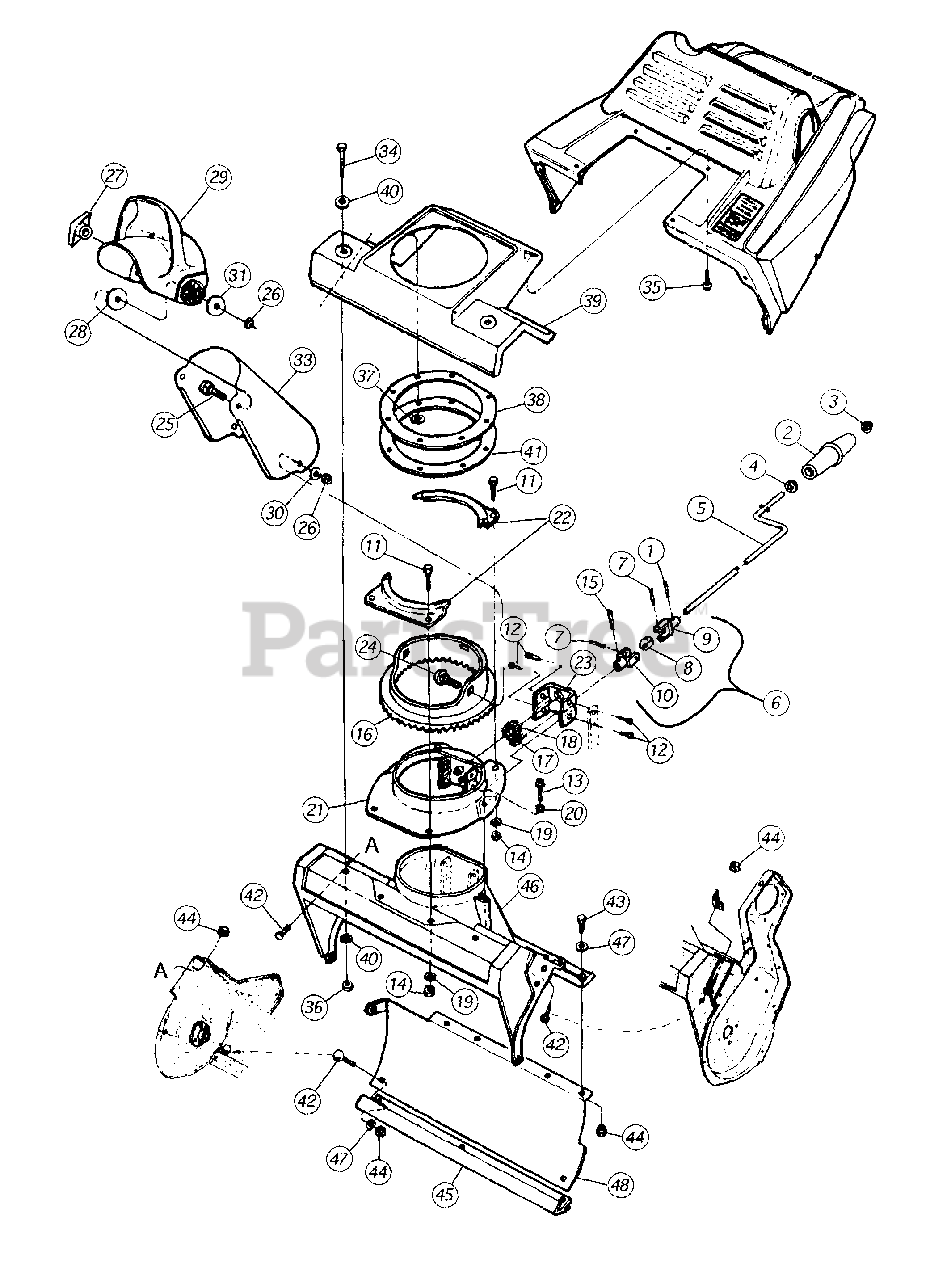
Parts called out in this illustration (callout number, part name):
1	Pin, Roll: 1/8 x .63
2	Chute Rotating Knob
3	Push Cap
4	Flat Washer
5	Chute Crank
6	U-Joint Assembly
7	Pin, Roll: 5/32 x .88
8	Connector, U-Joint
9	Clevis, Rear U-Joint
10	Clevis, Front U - Joint
11	Hex Screw: 1/4-20 x .75 Gr 5
12	Hex Screw: 1/4 x .50
13	Hex Screw
14	Top Lock Nylon Insert
15	Cotter Pin: 1/8 Dia. x 1.25
16	Chute Base: Black
17	Gear, Drive
18	Gear, Idler
19	Flat Washer
20	Flat Washer
21	Plate, Chute Base
22	Retainer, Chute Base
23	Mounting Bracket
24	Carriage Bolt
25	Carriage Screw: 5/16-18 X 1.0
26	Hex Lock Nut: 5/16-18
27	Knob Assembly
28	Rubber Washer: .50 X 1.50 X .08
29	Chute Deflector
30	Flat Washer
31	Flat Washer
35	Tap Screw
36	Sems Nut: 1/4-20
37	Nut, Push On
38	Chute Gasket
39	Chute Base Cover
40	Flat Washer
41	Retainer, Gasket
42	Carriage Bolt: 1/4-20 X .75
43	Hex Screw: 1/4-14 x .60
44	Top Lock Nylon Insert
45	Shave Plate
46	Auger Housing
47	Flat Washer
